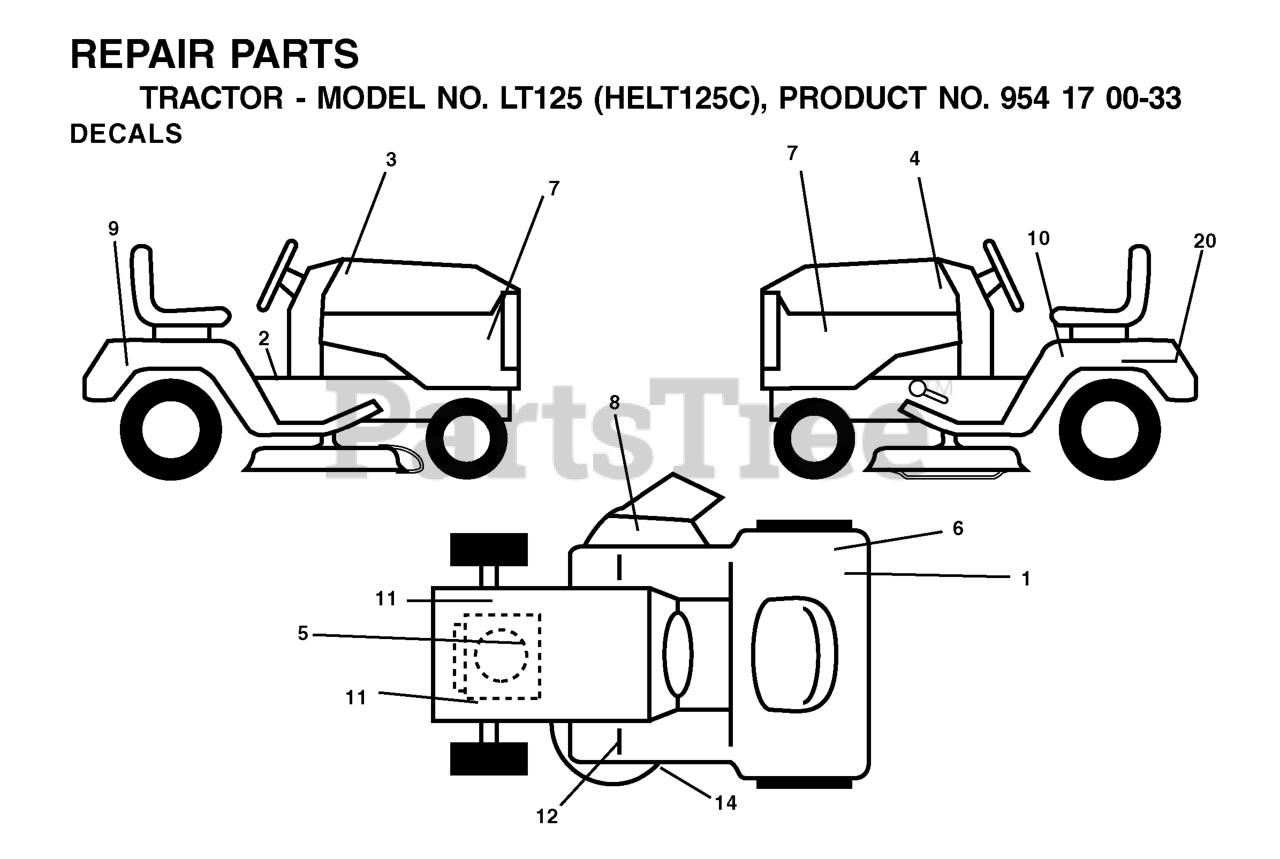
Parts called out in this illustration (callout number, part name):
1	DECAL CERTIFICATION
2	DECAL PARK BRAKE
5	DECAL ENGINE HP
6	DECAL EUROPE STANDARD CE
7	DECAL PNL SIDE
8	DECAL MOWER CUT/FINGER
9	DECAL FENDER HUSQ
10	DECAL READ OWNER'S MAN SYMS
12	DECAL
14	DECAL V-BELT SCHEMATIC
20	DECAL BTRY SYMBOLS
